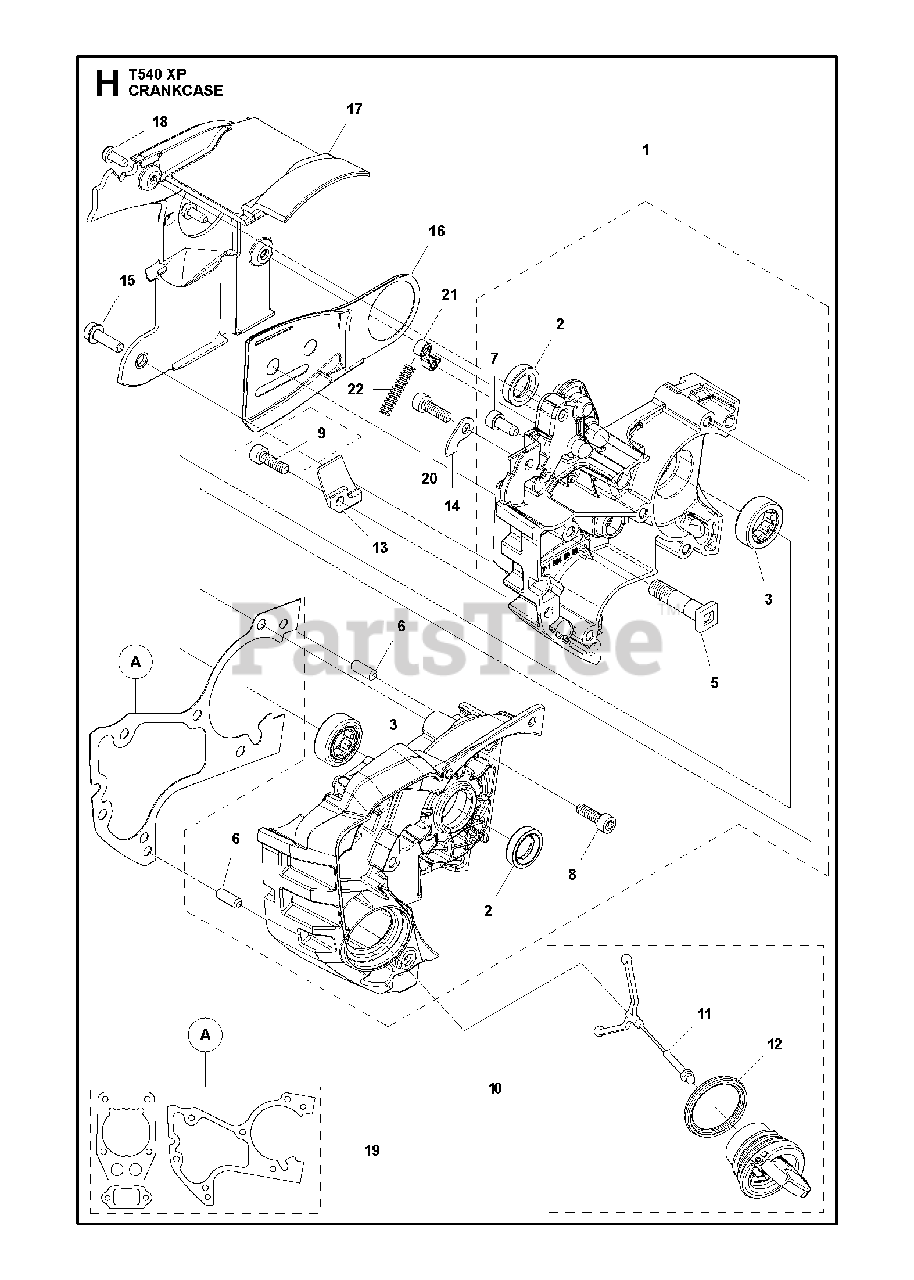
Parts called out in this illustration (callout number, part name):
1	CRANKCASE ASSY SPARE PART
2	RADIAL SEAL
3	ROLLER BEARING
5	BAR BOLT
6	PIN 5X14
7	SCREW ITXSCT
8	SCREW ITXSCM
9	SCREW ITXSCM
10	TANK CAP ASSY
11	TANK LOCK
12	SEALING
13	CHAIN CATCHER
16	CHAIN GUIDE PLATE
17	COVER LID ASSY
18	SCREW CITXPANT
19	GASKET KIT
20	SCREW ITXSCM
22	LOCK SPRING
